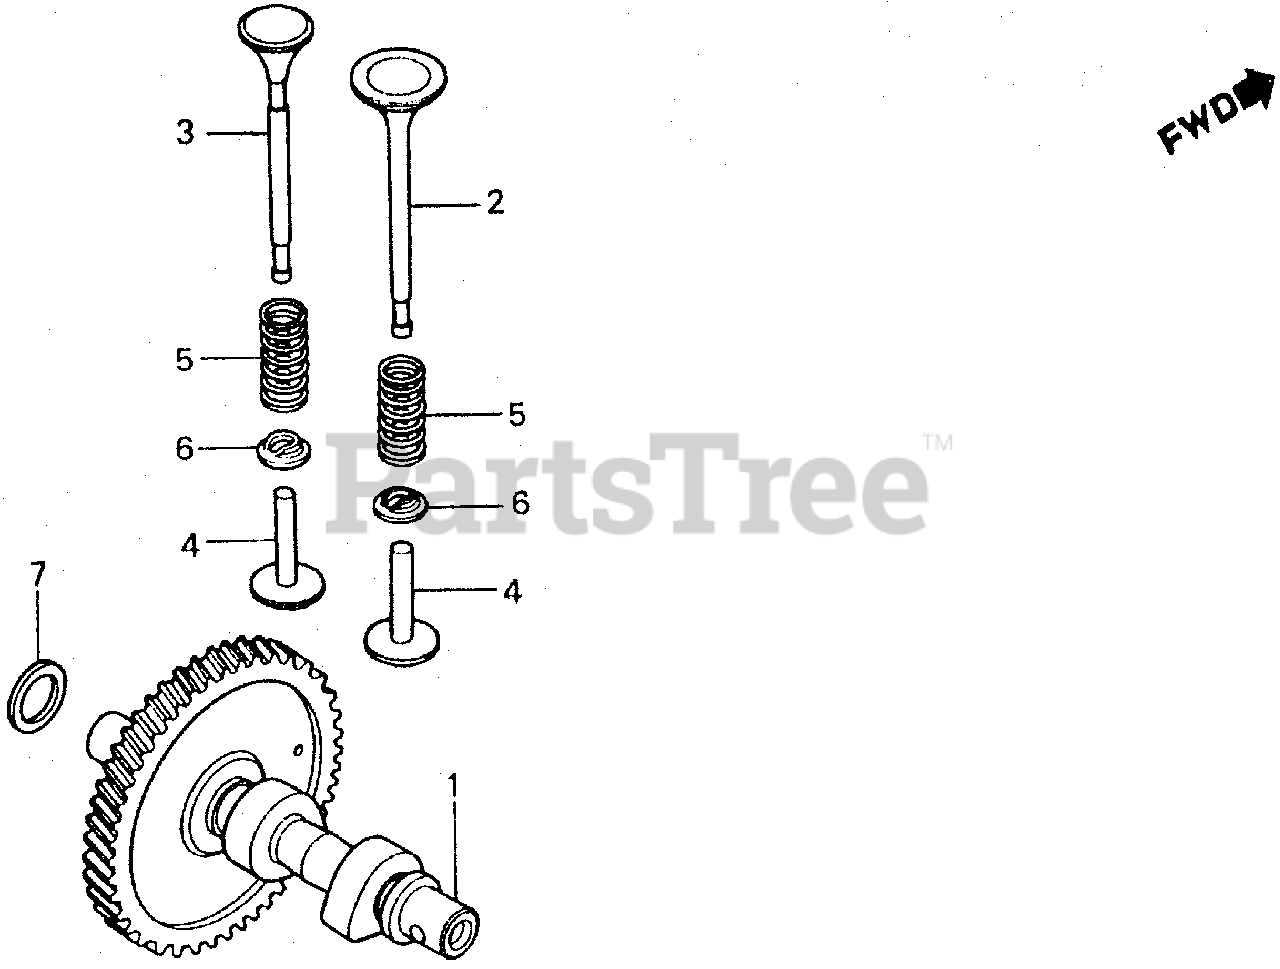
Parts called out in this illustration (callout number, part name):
2	VALVE, IN.
3	VALVE, EX.
4	LIFTER, VALVE (39.6MM)
4	LIFTER, VALVE (39.9MM)
5	SPRING, VALVE
6	RETAINER, VALVE SPRING
7	WASHER, THRUST (18MM)
